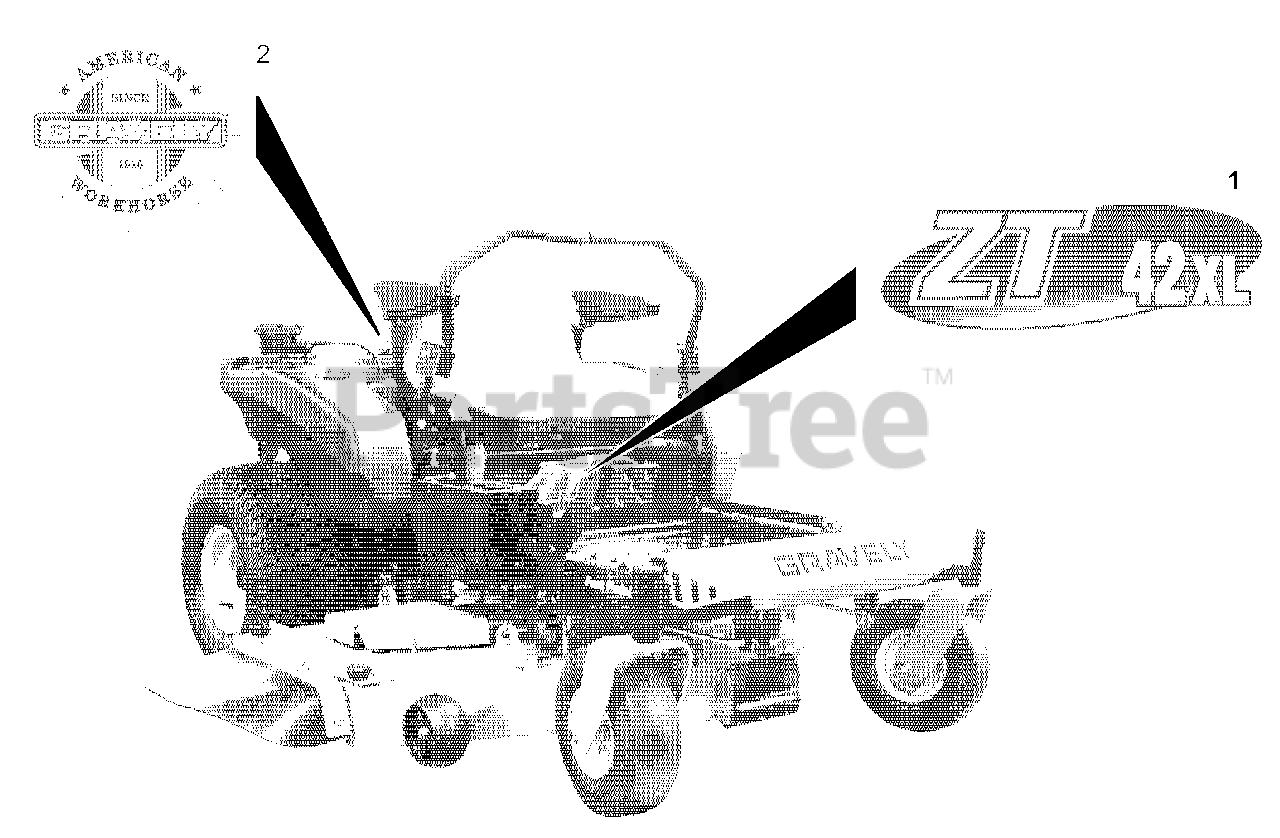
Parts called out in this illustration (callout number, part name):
1	DECAL, ZT 42 XL
1	DECAL, ZT 48 XL
1	DECAL, ZT 54 XL
2	DECAL, GRAVELY HERITAGE-LARGE
